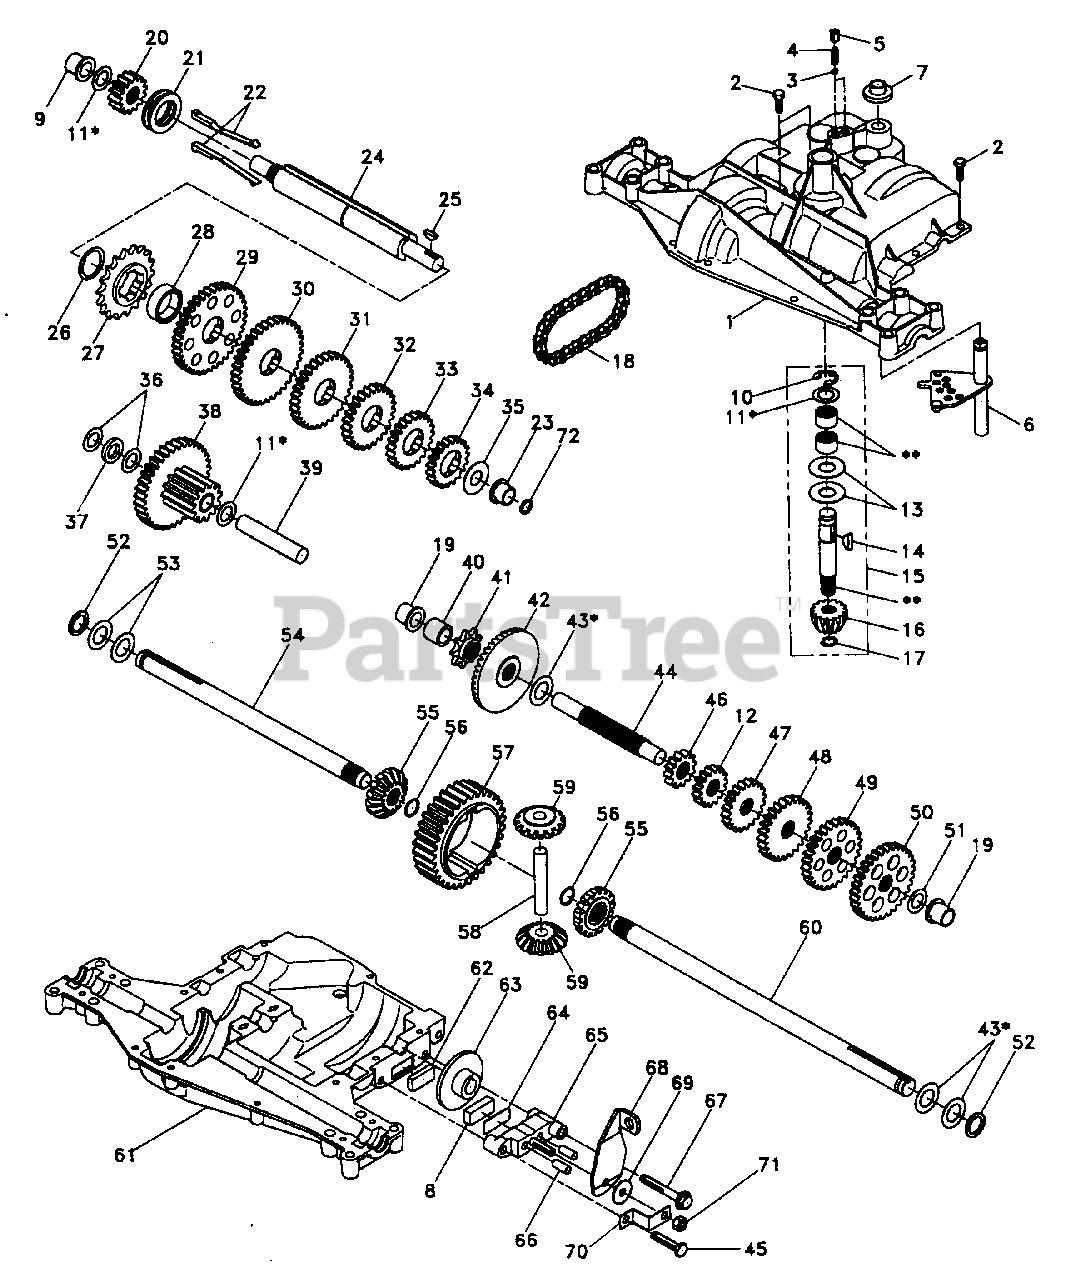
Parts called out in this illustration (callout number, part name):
1	Housing, Upper (AYP part number)
2	Screw, Tapping, Large 1/4-20 x .734 (AYP part number)
3	Ball, Detent (AYP part number)
4	Spring, Detent (AYP part number)
5	Screw, Set (AYP part number)
6	Kit, Shifter Assembly (AYP part number)
7	Boot, Shifter (AYP part number)
8	Puck, Friction (AYP part number)
9	Bearing, Flange (AYP part number)
10	Ring, Retaining
11	Assembly, Kit, Shim, .625 Shaft (AYP part number)
12	Gear, Spur, 15 Teeth (AYP part number)
13	Washer, Plain .632 x 1.38 x .046 (AYP part number)
14	Key, Woodruff, #9 (AYP part number)
15	Assembly, Kit, Input Shaft (AYP part number)
16	Pinion, Bevel, 14 Teeth (AYP part number)
17	Ring, Retaining (AYP part number)
18	Chain, 24 Pitches (AYP part number)
19	Bearing, Flange (AYP part number)
20	Gear, Spur, 14 Teeth (AYP part number)
21	Collar, Clutch (AYP part number)
22	Assembly, Kit, Clutch Keys (AYP part number)
23	Bearing, Flange (AYP part number)
24	Shaft, Intermediate (AYP part number)
25	Key, Woodruff, #61 (AYP part number)
26	Ring, Retaining (AYP part number)
27	Sprocket, 18 Teeth (AYP part number)
28	Spacer (AYP part number)
29	Gear, Spur, 37 Teeth (AYP part number)
30	Gear, Spur, 35 Teeth (AYP part number)
31	Gear, Spur, 30 Teeth (AYP part number)
32	Gear, Spur, 25 Teeth (AYP part number)
33	Gear, Spur, 22 Teeth (AYP part number)
34	Gear, Spur, 19 Teeth (AYP part number)
35	Washer, Plain .640 x 1.37 x .061 (AYP part number)
36	Washer, Plain .632 x 1.00 x .026 (AYP part number)
37	Spacer .630 x 1.00 x .169 (AYP part number)
38	Assembly, Gear, Combination, 12 & 35 Teeth (AYP part number)
39	Shaft, Idler (AYP part number)
40	Spacer .633 x .87 x .755 (AYP part number)
41	Sprocket, 9 Teeth (AYP part number)
42	Gear, Bevel, 42 Teeth (AYP part number)
43	Assembly, Kit, Shim, .750 Shaft (AYP part number)
44	Shaft, Drive (AYP part number)
45	Screw, Tapping, Large 5/16-18 x 1.44 (AYP part number)
46	Gear, Spur, 12 Teeth (AYP part number)
47	Gear, Spur, 20 Teeth (AYP part number)
48	Gear, Spur, 25 Teeth (AYP part number)
49	Gear, Spur, 28 Teeth (AYP part number)
50	Gear, Spur, 31 Teeth (AYP part number)
51	Washer, Plain .632 x 1.00 x .060 (AYP part number)
52	Washer, Neoprene (AYP part number)
53	Washer, Plain .758 x 1.25 x .031 (AYP part number)
54	Axle, L.H. (AYP part number)
55	Gear, Miter, 15 Teeth (AYP part number)
56	Ring, Retaining (AYP part number)
57	Gear, Spur, 32 Teeth (AYP part number)
58	Shaft, Cross (AYP part number)
59	Gear, Miter, 15 Teeth (AYP part number)
60	Axle, R.H. (AYP part number)
61	Housing, Lower (AYP part number)
62	Puck, Friction (AYP part number)
63	Disc, Brake (AYP part number)
64	Spacer (AYP part number)
65	Jaw, Brake (AYP part number)
66	Pin, Dowel (AYP part number)
67	Screw, Tapping 5/16-18 x 2.25 (AYP part number)
68	Lever, Actuating (AYP part number)
69	Washer, Plain .321 x 1.00 x .055 (AYP part number)
70	Bracket, Anti-Rotation (AYP part number)
71	Locknut 5/16-24 (AYP part number)
72	Seal, Oil (AYP part number)
73	Grease (AYP part number)
